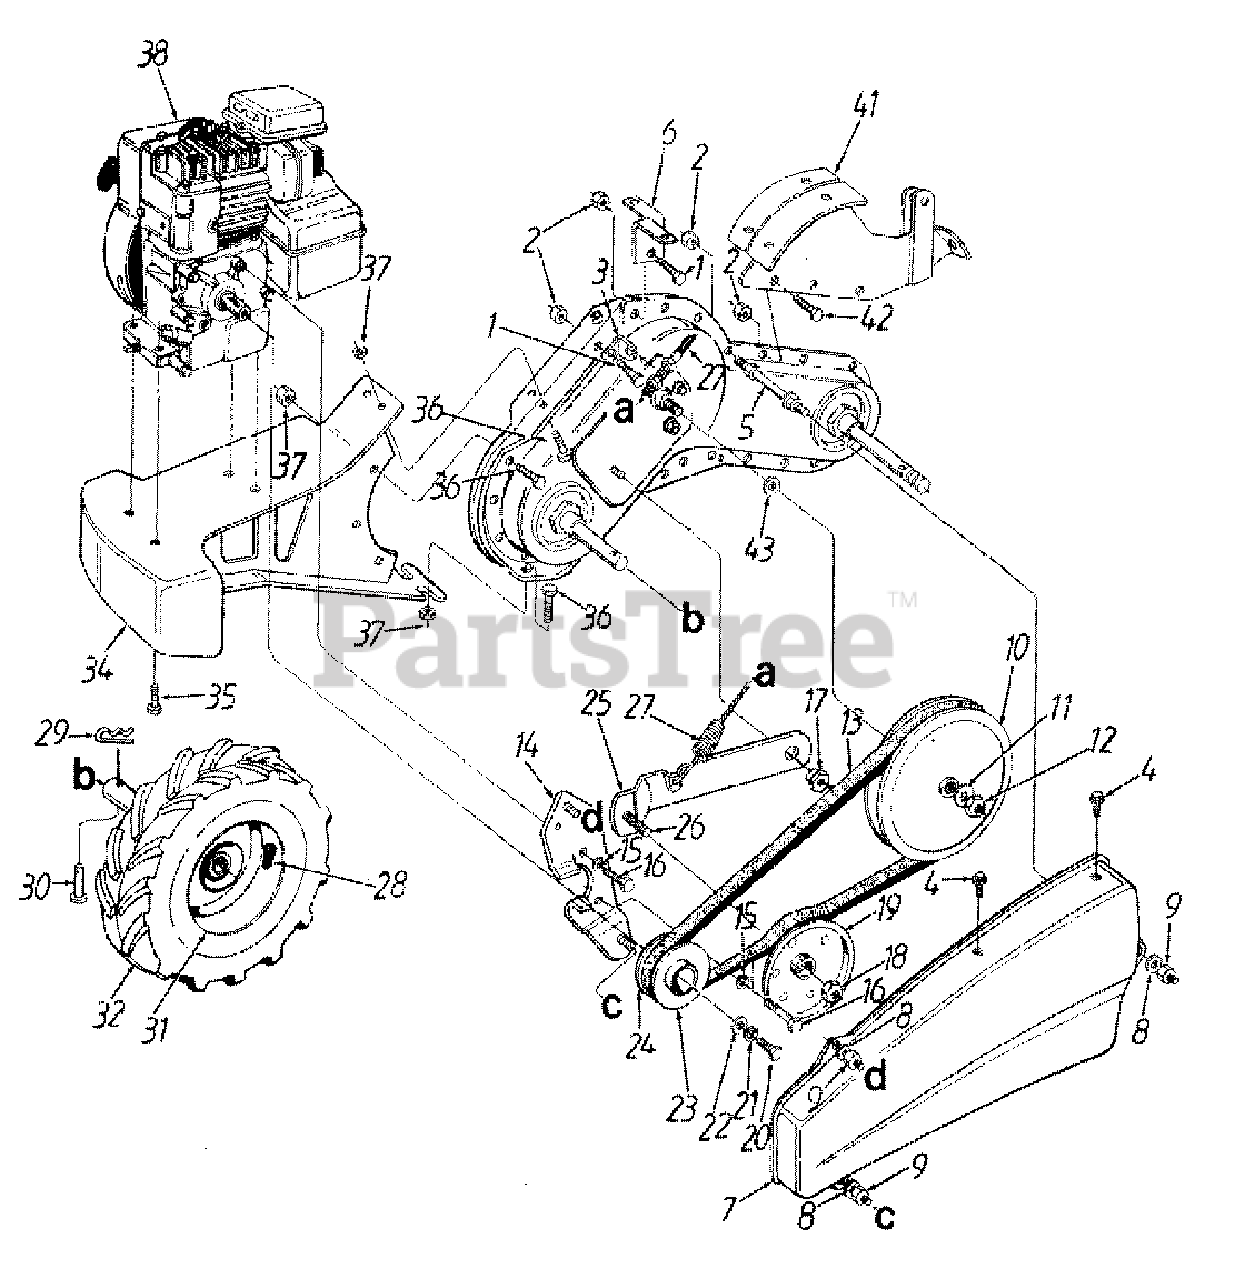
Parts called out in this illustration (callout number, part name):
1	Hex Bolt 5/16-18 x .75" Lg.
2	Hex Top L-Nut 5/16-18 Thd.
3	Cable Mtg. Bracket
4	Torx Mach. AB-Tap Scr. 1/4 x .6" Lg
5	Belt Cover Bolt
8	Fl-Wash. .281" I.D. x .5" O.D.
9	Hex Cap Nut 1/4-28 Thd.
10	Flat Pulley 8" O.D.
11	Bell-Wash. .38" I.D. x .88" O.D.
12	Hex Flange Nut.
13	"V"-Belt
16	Hex Bolt 5/16-24 x .62" Lg.
17	Shld. Nut
18	Hex Jam L-Nut 3/8-16 Thd.
19	Fl-Idler w/Flanges
20	Hex Bolt 3/8-24 x 1" Lg.
21	L-Wash. 3/8" I.D.
22	Fl-Wash. 3/8" I.D. x 1" O.D.
23	Outer Engine Pulley Half
24	Inner Engine Pulley Half
26	Hex Bolt 3/8-16 x 1.25" Lg.
27	Clutch Cable
28	Air Valve
29	Hairpin Clip
34	Frame Counterweight
35	Hex TT-Tap Scr. 3/8-16 Thd.
36	Hex Bolt 5/16-18 x 1" Lg. (Gr. 5)
37	Hex Flange L-Nut 5/16-18 Thd.
38	Engine
43	Wash. Fl. .635 I.D. x .930 O.D. x .03
